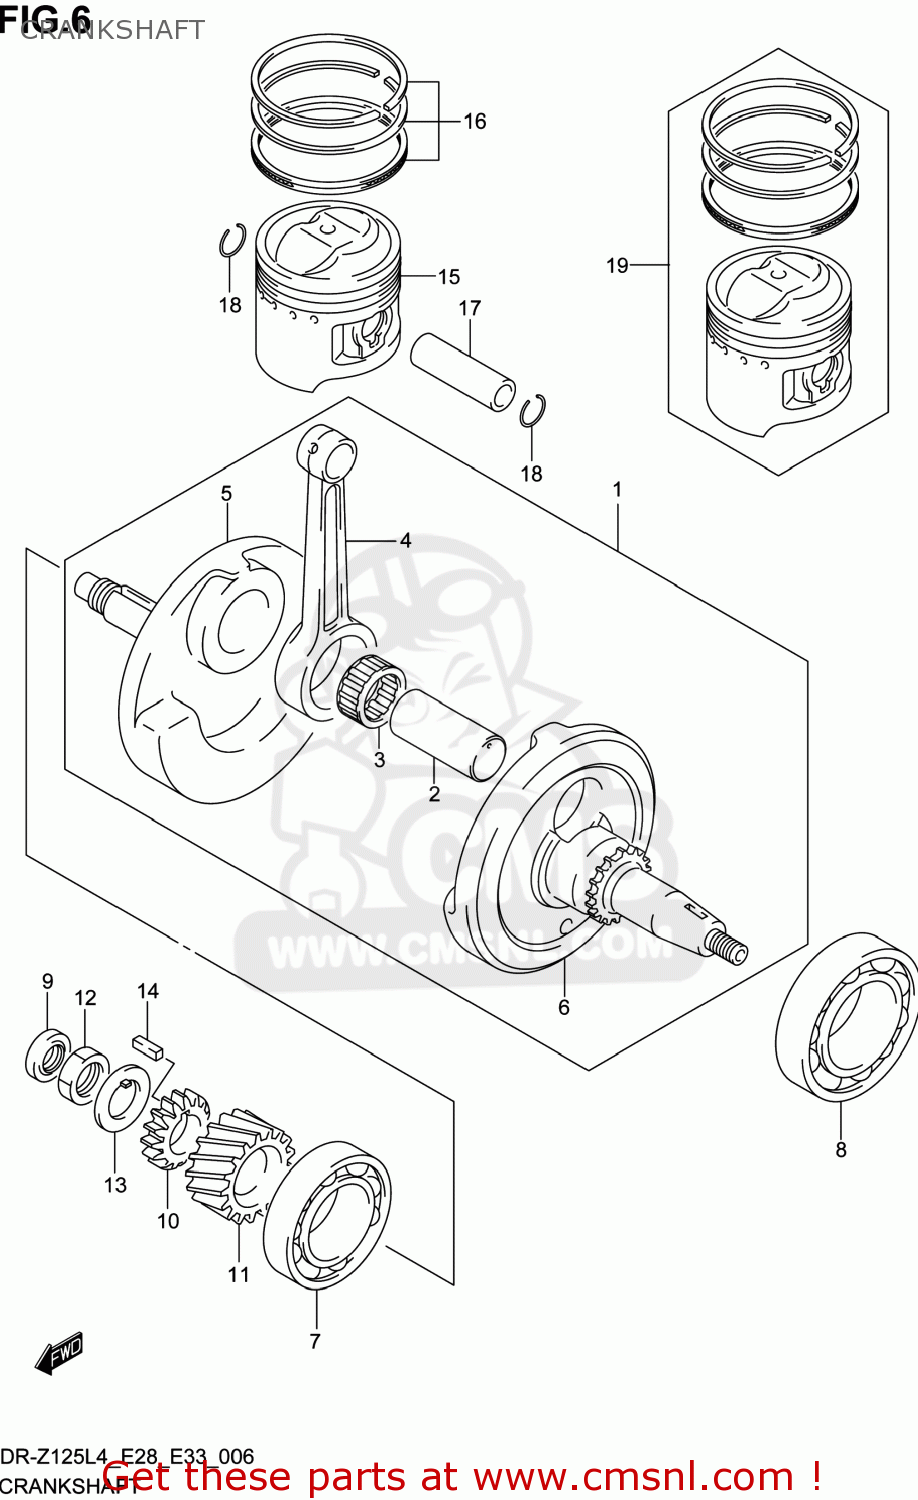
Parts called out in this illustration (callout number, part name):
1	CRANKSHAFT ASSY
2	PIN,CRANK
3	BEARING(28X36X15.8)
4	CONNROD
5	CRANKSHAFT,R
6	CRANKSHAFT,L
7	BEARING(28X68X18)
8	BEARING(35X72X17)
9	SEAL,OIL(12X21X7)
10	GEAR,OIL PUMP DRIVE
11	GEAR,PRIMARY DRIVE(NT:17)
12	NUT
13	WASHER
14	KEY
15	PISTON
16	RING SET,PISTON
17	PIN,PISTON
18	RING,SNAP 14MM
19	PISTON SET(OS:0.5)
